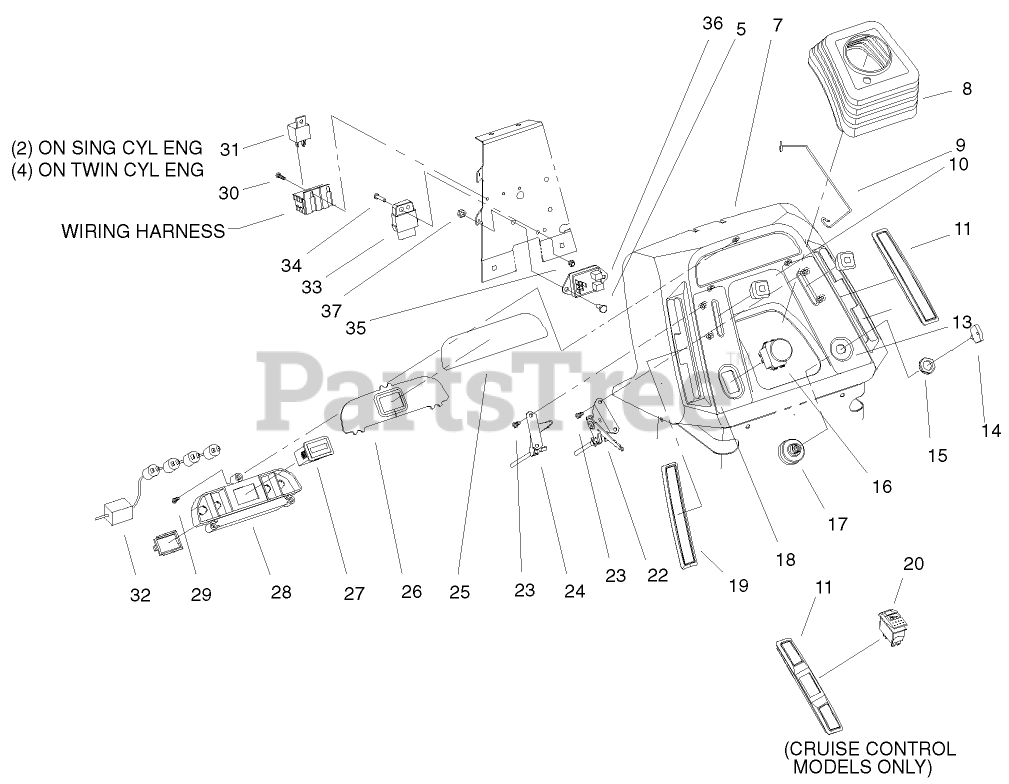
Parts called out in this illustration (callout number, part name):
5	SCREW-HH
8	BOOT-STEERING
9	CLIP-BOOT
11	COVER-SLOT, RH
13	DECAL-THROTTLE, IGNITION
13	DECAL-DASH
14	KEY-IGNITION
16	SWITCH-PTO,ON-ON-NONE
17	SWITCH-IGNITION
18	DECAL-PTO / CHOKE
18	DECAL-DASH, PTO/CHOKE
19	COVER-SLOT, LH
20	SWITCH-CRUISE
22	CONTROL-THROTTLE (TWIN)
24	CONTROL-CHOKE (TWIN)
26	LENS-DASH
27	HOURMETER
28	HOUSING-LIGHT, INDICATOR
29	SCREW
30	SCREW-PPHTF
31	RELAY
32	HARNESS-4 LAMP
33	MODULE-LOW VOLTAGE
35	NUT-LOCK, NI
36	MODULE-CLUTCH
37	NUT-LOCK, NI
